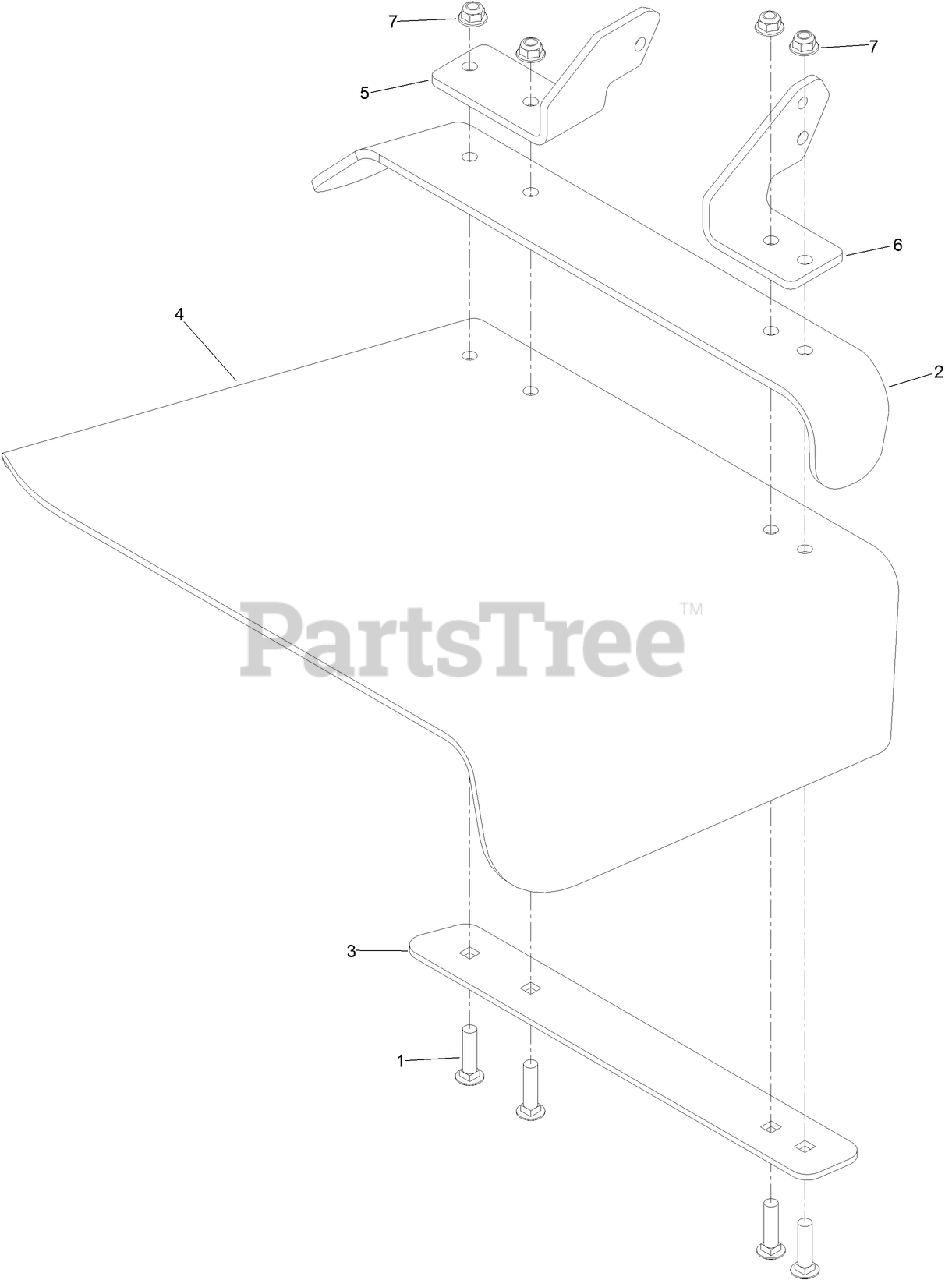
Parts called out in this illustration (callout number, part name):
1	SCREW-CARR
2	DEFLECTOR
3	STRAP-DISCHARGE
4	DEFLECTOR-RUBBER
5	PLATE-HINGE, REAR
6	PLATE-HINGE, FRONT
7	NUT-HF, NI
